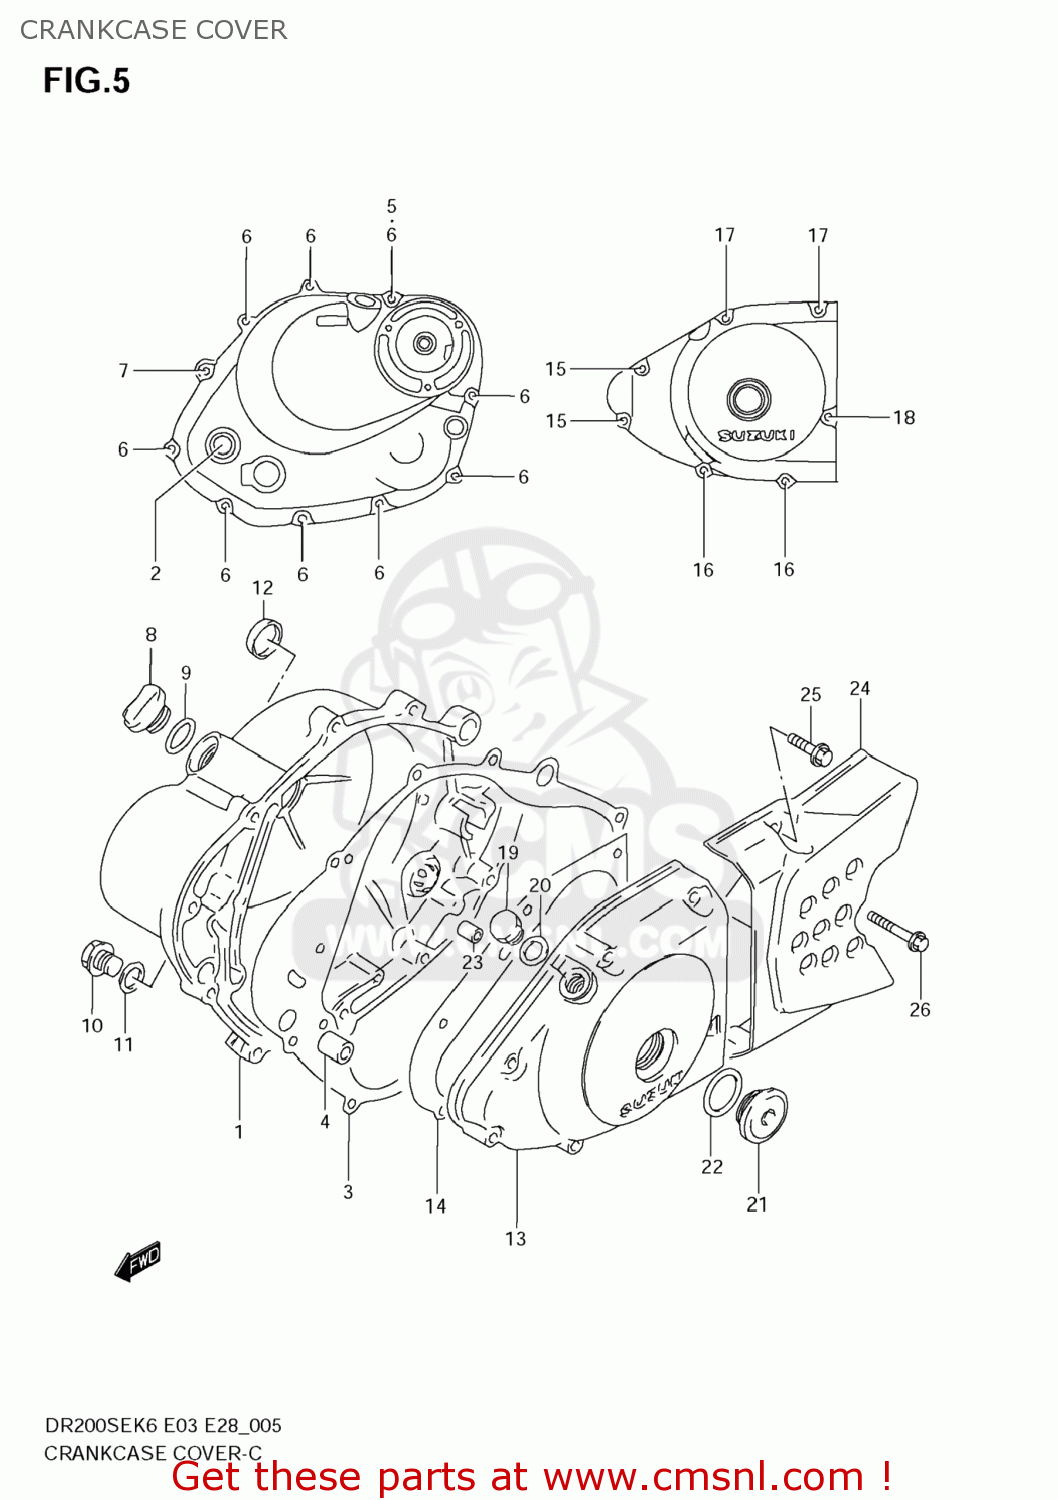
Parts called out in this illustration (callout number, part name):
1	COVER,CLUTCH
2	LENS,OIL LEVEL CHECK
3	GASKET,CLUTCH COVER (NAS)
4	PIN
5	GASKET(5.8X13X1.2) (NAS)
6	BOLT
7	BOLT
8	PLUG
9	O RING(D:3.1,ID:16.8)
10	PLUG(14X12)
11	GASKET(13.8X18.8X4.8) (NAS)
12	PLUG,CLUTCH COVER KICK
13	COVER,MAGNETO
14	GASKET,MAGNETO COVER (NAS)
15	BOLT
16	BOLT
17	BOLT
18	BOLT
19	PLUG,12X9
20	GASKET(12.1X16.2X3.7) (NAS)
21	PLUG(26X9)
22	O RING(D:3.1,ID:22.7)
23	PIN
24	COVER,ENGINE SPROCKET
25	BOLT
26	BOLT
